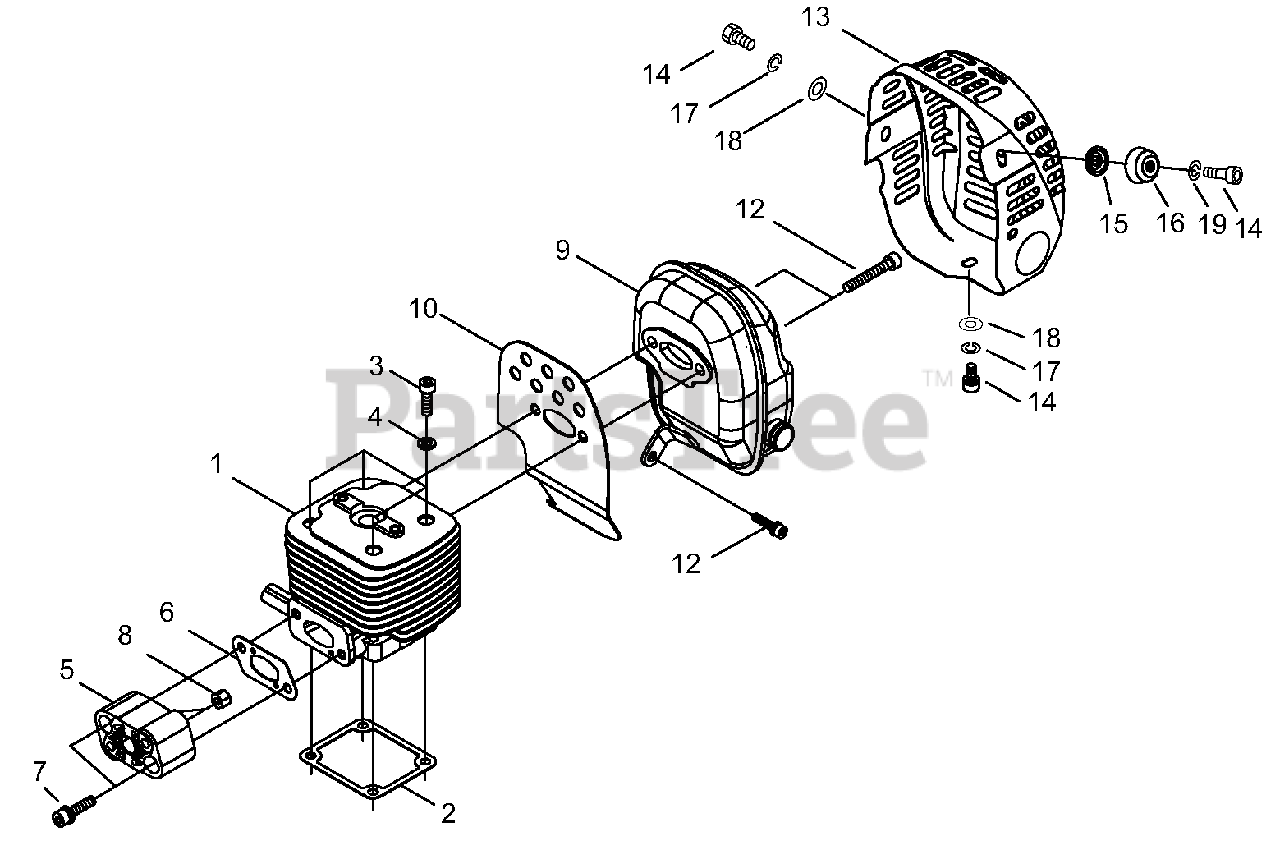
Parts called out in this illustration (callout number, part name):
1	CYLINDER
2	GASKET, CYLINDER
3	SCREW - 5X25
4	LOCKWASHER - 5
5	INSULATOR, INTAKE
6	GASKET, INTAKE
7	SCREW - 5X25
8	NUT
9	MUFFLER
10	SHIELD, EXHAUST
11	SCREW - 6X25
12	SCREW - 5X12
13	COVER, EXHAUST
14	SCREW - 5X10
15	WASHER
16	COVER
17	LOCKWASHER - 5
18	WASHER - 5
19	LOCKWASHER - 5
